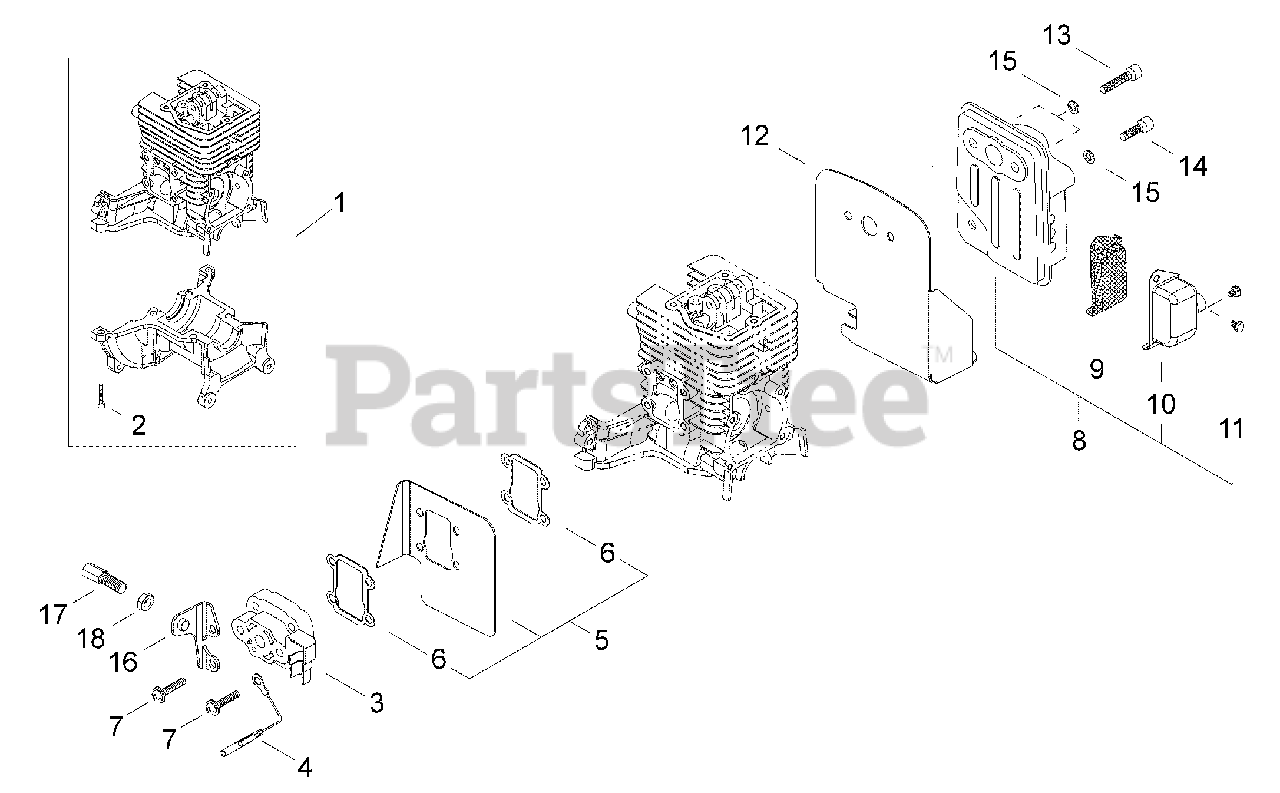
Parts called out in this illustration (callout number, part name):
1	CYLINDER BLOCK SET
2	SCREW - 5X16
3	VALVE, REED
4	LEAD - GROUND
5	INTAKE SHIELD ASSY
6	SHIELD, INTAKE
7	SCREW - 5X25
8	MUFFLER ASSY
9	SCREEN, SPARK ARRESTOR
10	GUIDE, EXHAUST
11	SCREW - 4X6
12	DEFLECTOR, HEAT
13	SCREW - 5X25
14	SCREW - 5X16
15	WASHER - 5
16	BRACKET, THROTTLE CABLE
17	NUT, CABLE ADJUST
18	LOCKNUT - 6
